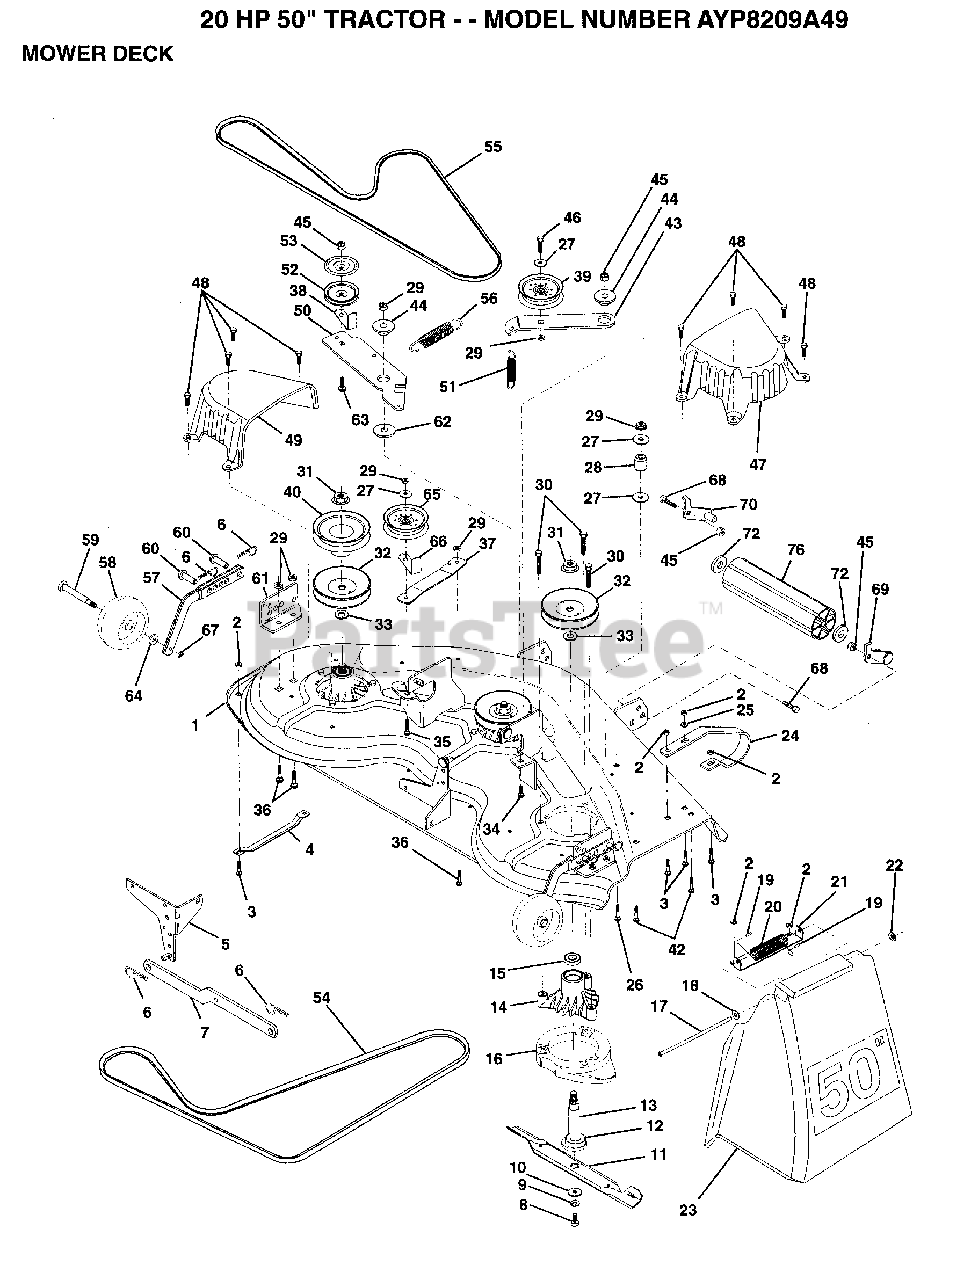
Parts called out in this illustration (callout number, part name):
1	DECK ASM MWR 50VT
2	NUT
4	RUNNER-LH M
5	BRKT.ASM.SW.44/50
8	BLADE BOLT
10	WASHER.HARD.BLADE
11	"BLADE.50"" HD"
12	BEARING.BALL
13	SHAFT.ASM.W/BRNG
14	HOUSING.MAND.44.V
15	BEARING
17	ROD-HINGE T
18	WASHER
19	CAP-SLEEVE LT
20	SPRING TORSION
21	BRKT DEFLECTOR
22	NUT PUSH M
23	DEFLECTOR
24	"RUNNER RH 50"" DK"
25	WASHER M
26	BOLT
27	WASHER
29	NUT
33	WASHER
34	BOLT.3/8-14X1.25
35	BOLT
36	BOLT D
37	STIFFENER.ARM.IDL
39	FLAT IDLER PULLEY
40	"PULLEY.DRIVEN.44"""
42	BOLT
43	"ARM.IDLER.SEC.44"""
44	SPACER RETAINER
47	"COVER.MAND.RH.44"""
48	SCREW.1/4-20X5/8
49	COVER.MANDREL.LH
50	ARM.IDLER.PRIMARY
51	"SPRING.SEC.44""VEN"
52	PULLEY.IDLER.VGRO
53	SHIELD.IDLER.44.V
54	BELT V PRIM 50
55	BELT.V.GDRIVE.95
56	SPRING.EXT.DECK.
57	BAR.ASM.GUAGE.WHL
58	WHEEL GAGE DONUT
59	BOLT.SHOULDER
60	PIN.CLEVIS
61	BRACKET.GUAGE.WHL
62	HARDENED WASHER
63	BOLT.3/8-16X1.50
64	WASHER
65	IDLER-FLAT T
67	LOCKNUT
68	BOLT
72	WASHER
